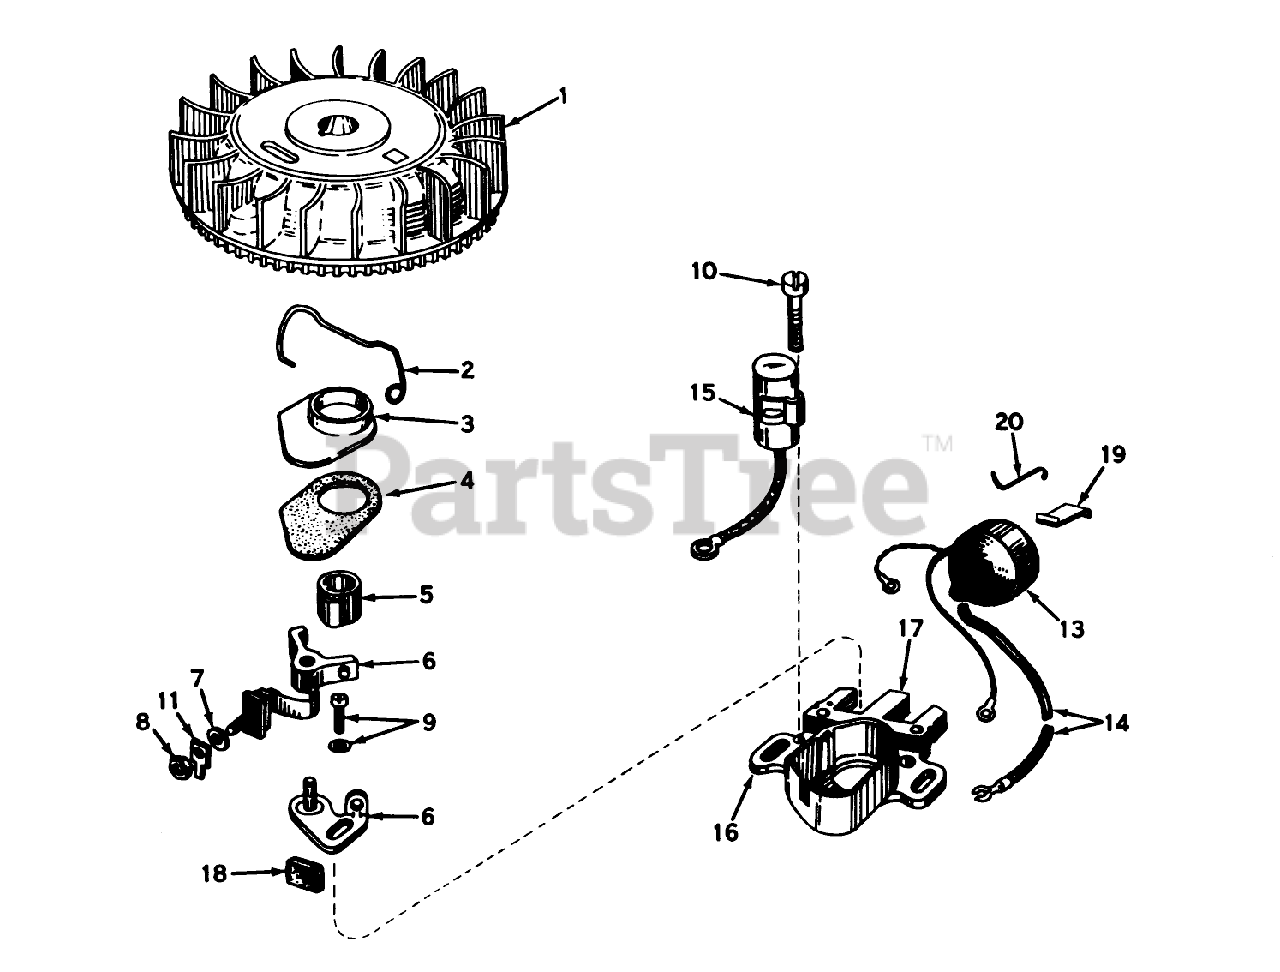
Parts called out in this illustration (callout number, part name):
1	FIywheel
2	Spring Breaker Box
3	Cover, Dust
4	Gasket Dust Cover
5	Cam, Breaker
6	Breaker Assy.
7	Washer
8	DECAL
9	Breaker Screw
10	Condenser Screw
11	Terminal, Ground
13	Coil Assy. (Incl. No. 12)
14	Wire, Lead
15	Condenser
16	Core Plate
17	Stator Assy., (Incl. Nos. 2, 3, 5 thru 14 16 thru 19)
18	Felt,Cam Wiper
19	Spring Coil Wedge
20	Clip, Coil
